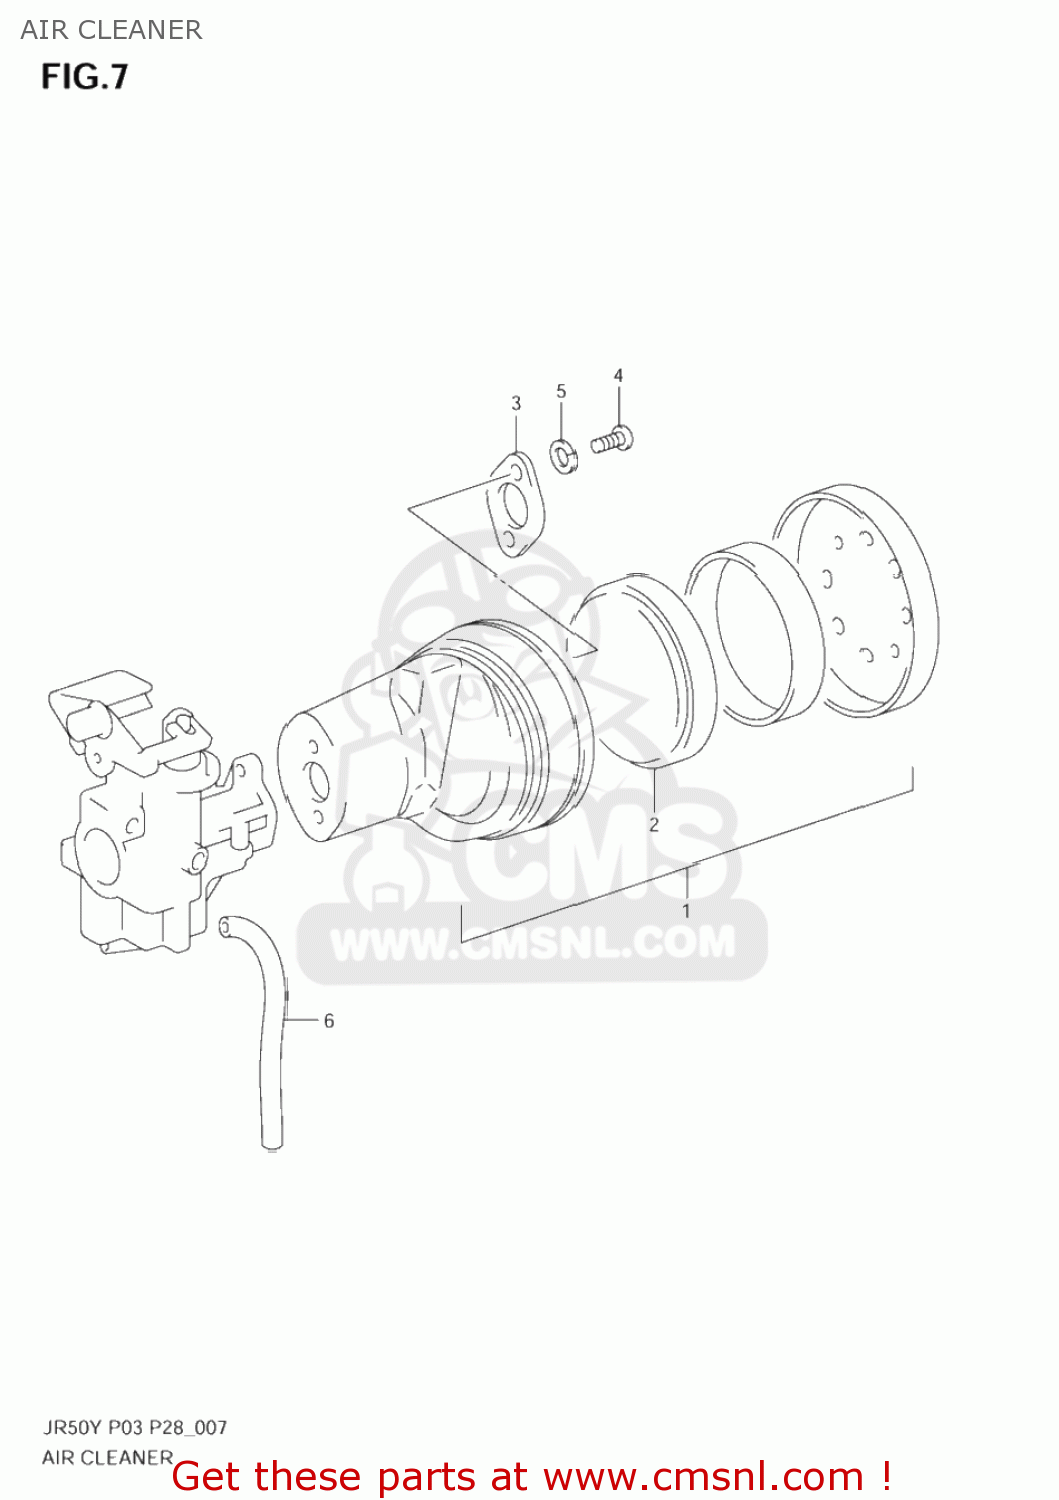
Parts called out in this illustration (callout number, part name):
1	CLEANER ASSY,AIR
2	FILTER,AIR CLEANER
3	PLATE,AIR CLEANER
4	SCREW
5	LOCK,WASHER
6	HOSE(3X5X600)
